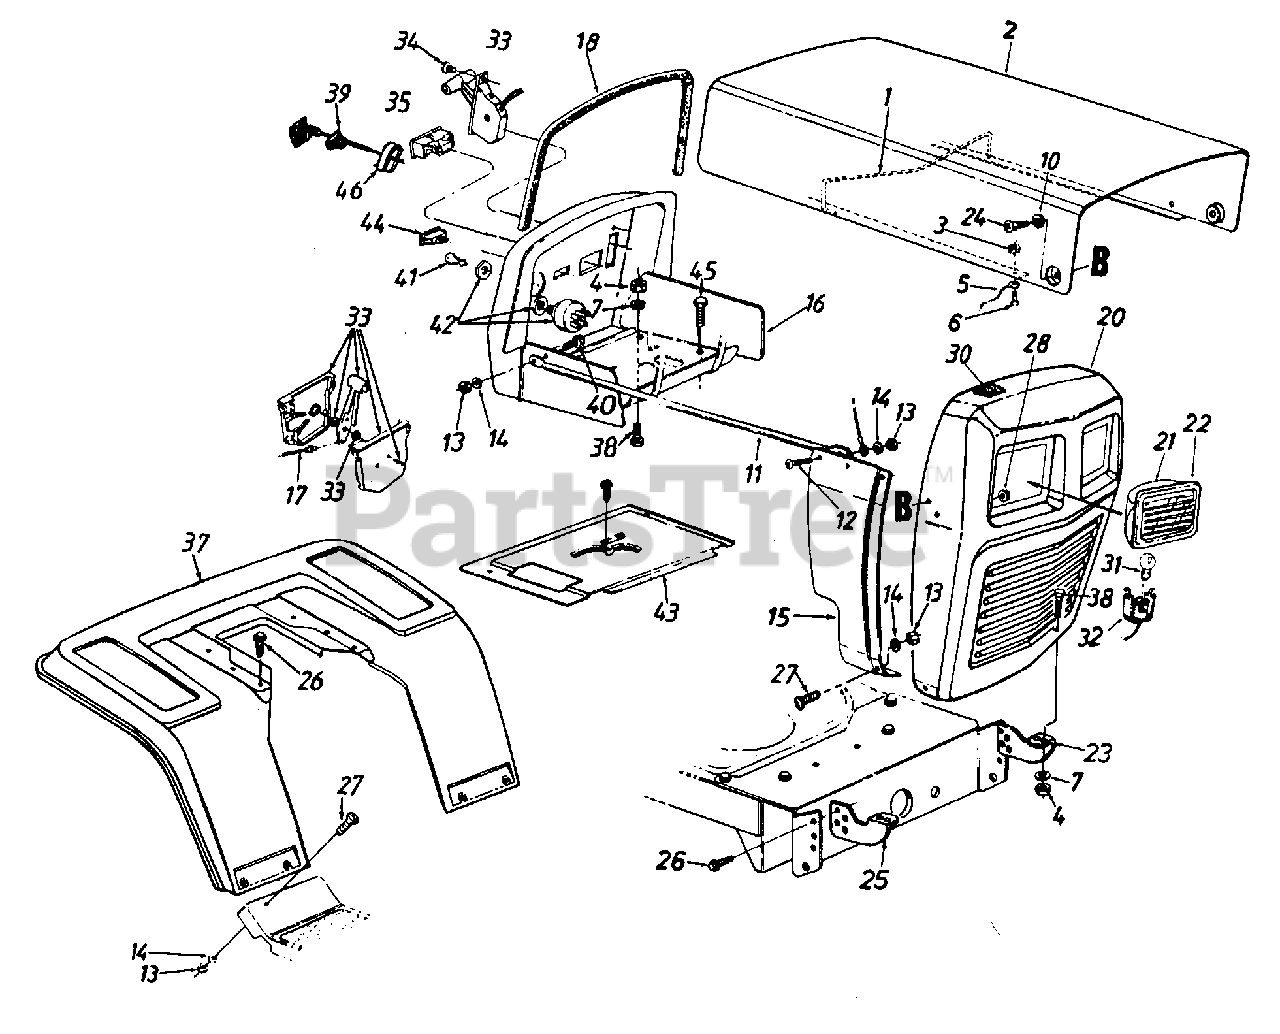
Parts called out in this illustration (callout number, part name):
1	Hood Spring
4	Hex Nut 5/16-18 Thd.*
5	Hood Stop 7" Lg.
6	Truss Hd. Scr. #10-24 x 1/2"
7	L-Wash. 5/16" I.D.
10	Washer .39" I.D. x .62" O.D.
11	Grille Support Rod
12	Truss Hd. Scr. 1/4-20 x .75"
13	Hex Nut 1/4-20 Thd.
14	L-Wash. 1/4" I.D.
18	Molding Strip 31" Lg.
22	Headlight Lens
25	Mounting Brkt.
26	Hex Wash. Hd. AB-Tap Scr. 5/16 x .75" Lg.
27	Carriage Bolt 1/4-20 x 2.0" Lg.
28	L-Nut 1/4-28 Thd.
30	Foam Strip 3/8 x 1-1/8 x 1-1/2
31	Bulb
32	Twist Lock Lamp Socket
33	Throttle Box Ass'y.
34	Truss Mach. AB-Tap Scr. #10 x .5" Lg.
35	Ammeter
39	Choke Control 29" Lg.
40	Hex Bolt 1/4-20 x .62" Lg.
41	Ignition Key
42	Ignition Switch
43	Shift Cover
44	Light Switch
45	Hex Wash. Hd. B-Tap Scr. 5/16-18 x .5" Lg.
46	Choke Retainer
